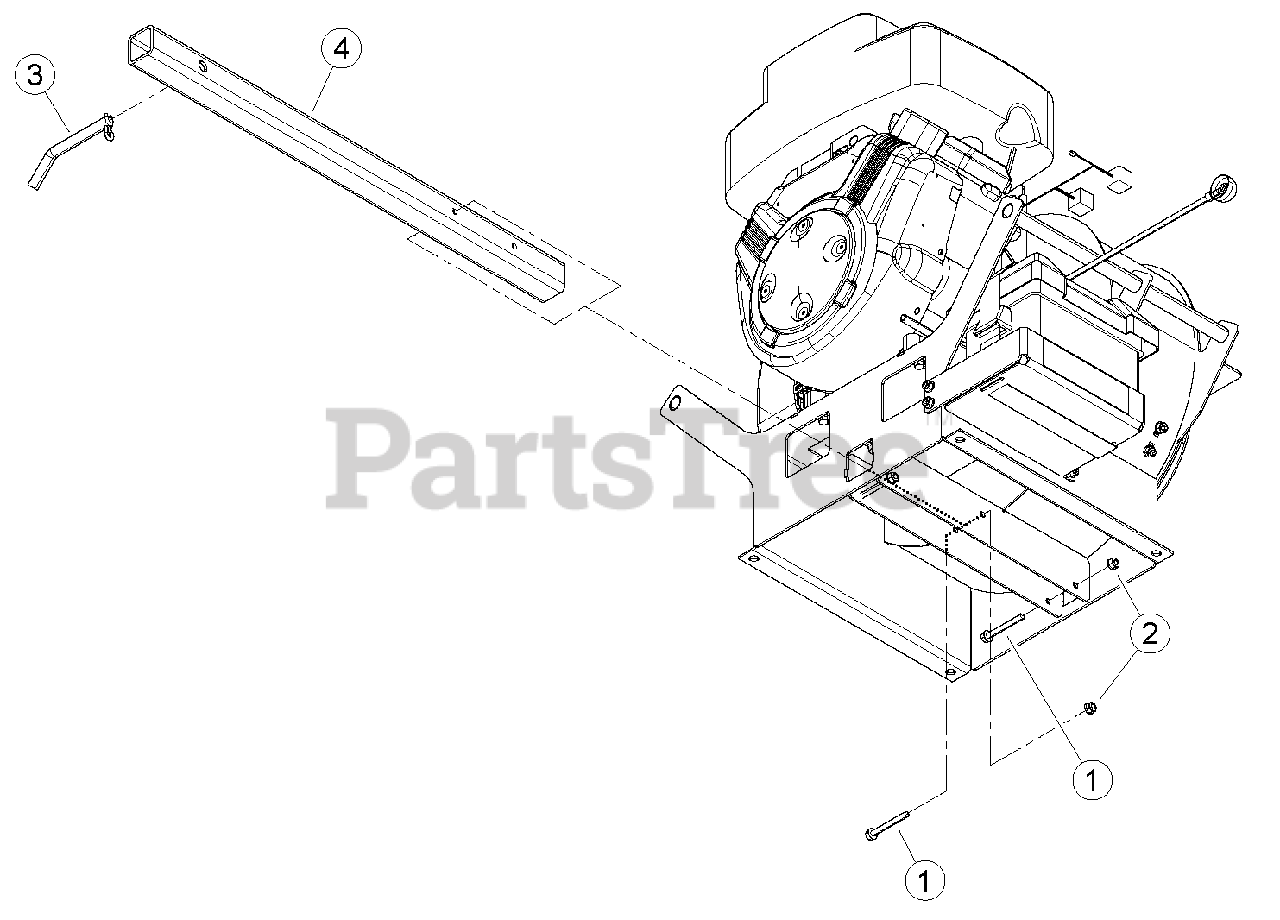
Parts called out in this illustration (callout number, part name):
1	BOLT, 5/16 X 2-3/4 FLANGE NC
2	NUT, 5/16-18 NYLOCK FLANGE
3	PIN, HITCH BENT ARM 5/8
4	TUBE, HITCH
